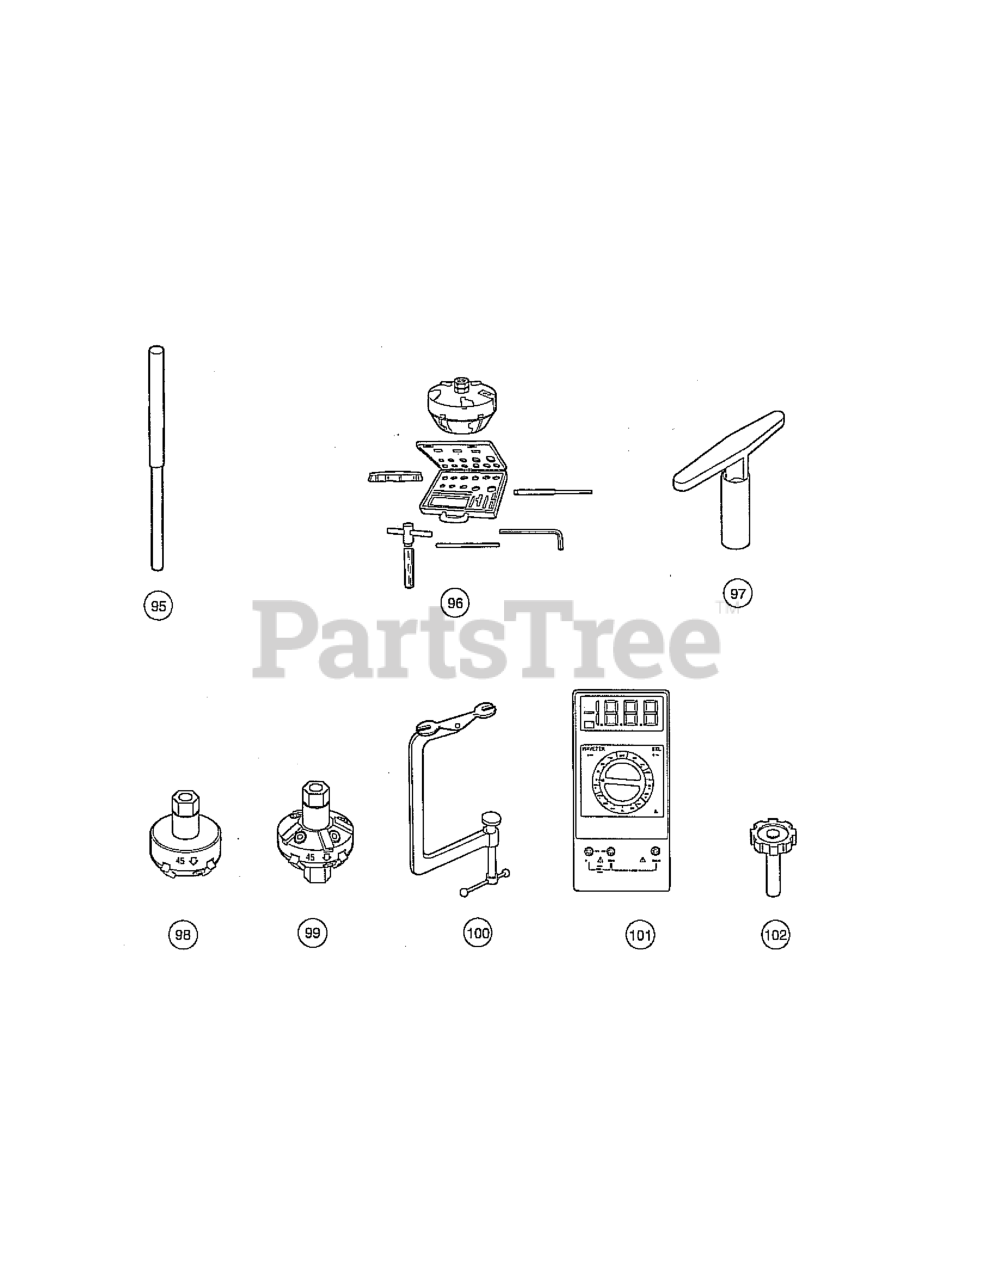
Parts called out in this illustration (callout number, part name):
95	VALVE SEAT CUTTER GUIDE
97	VALVE SEAT CUTTER "T" WRENCH
98	VALVE SEAT CUTTER 45 DEG 32 MM
99	CUTTER INTAKE VALVE ST 45/30
100	VALVE SPRING CMPR & ADAPTER
101	METER, WAVETEK VOLT-OHM
